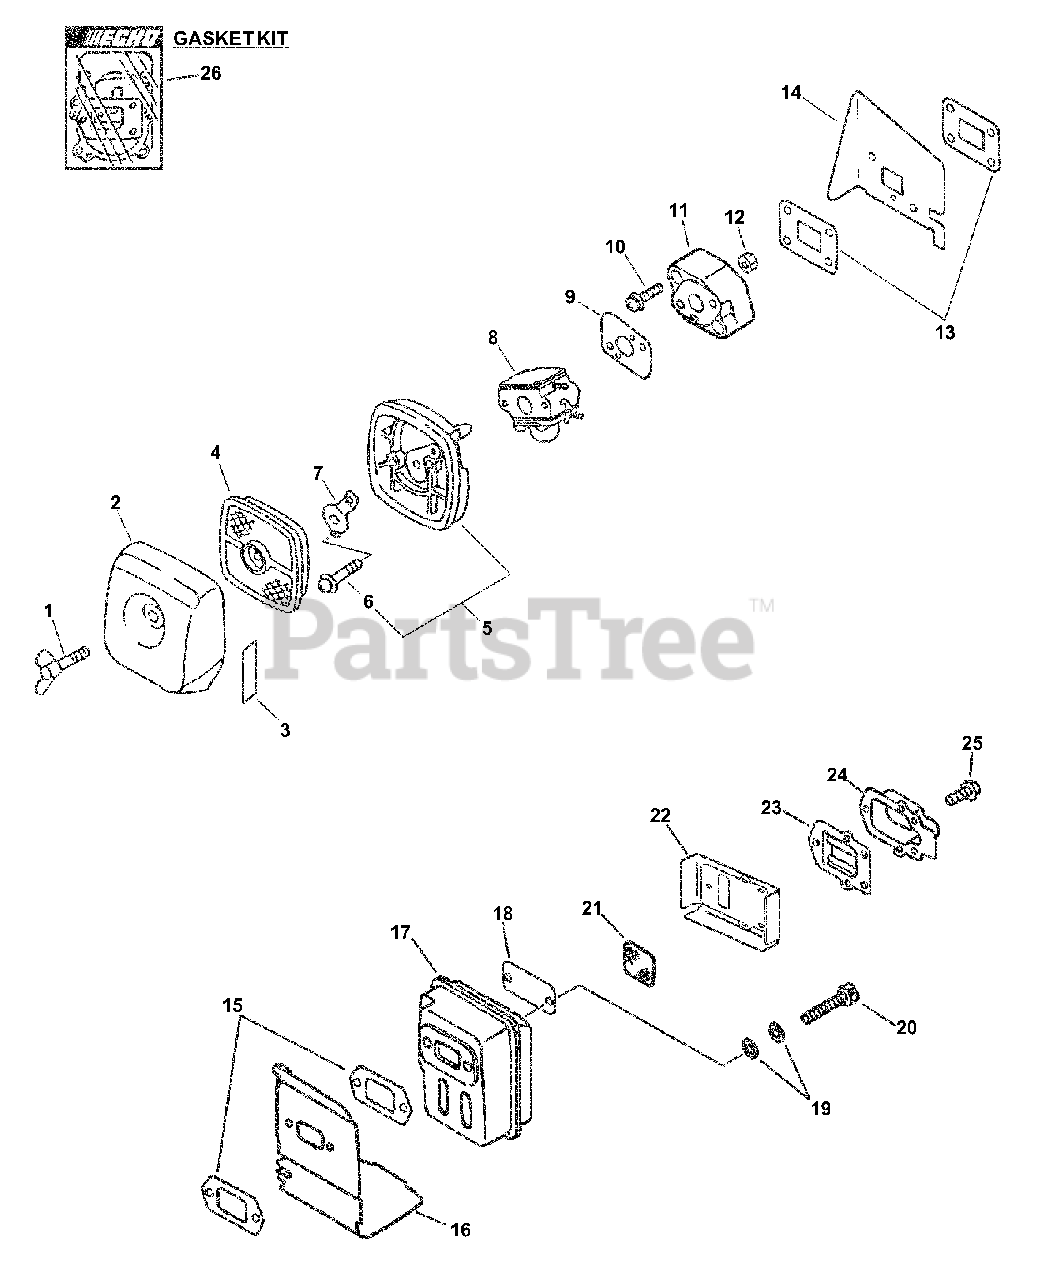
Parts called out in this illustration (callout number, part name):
1	THUMBSCREW
2	COVER, AIR FILTER - GRAY
3	LABEL - CHOKE
4	FILTER, AIR - SINGLE LAYER
5	AIR FILTER CASE ASSY
6	SCREW - 5X65
7	PLATE, PREVENT
8	CARBURETOR C1U-K62
9	GASKET, INTAKE
10	SCREW - 5X22
11	INSULATOR, INTAKE
13	GASKET, INTAKE
14	SHIELD, INTAKE
15	GASKET, EXHAUST
16	SHIELD, EXHAUST
17	MUFFLER
19	WASHER - CONICAL
20	SCREW - 5X55
21	SCREEN, SPARK ARRESTOR
22	GASKET, EXHAUST
23	GUIDE, EXHAUST - INNER
24	GUIDE, EXHAUST
25	SCREW - 4X12
26	GASKET KIT
